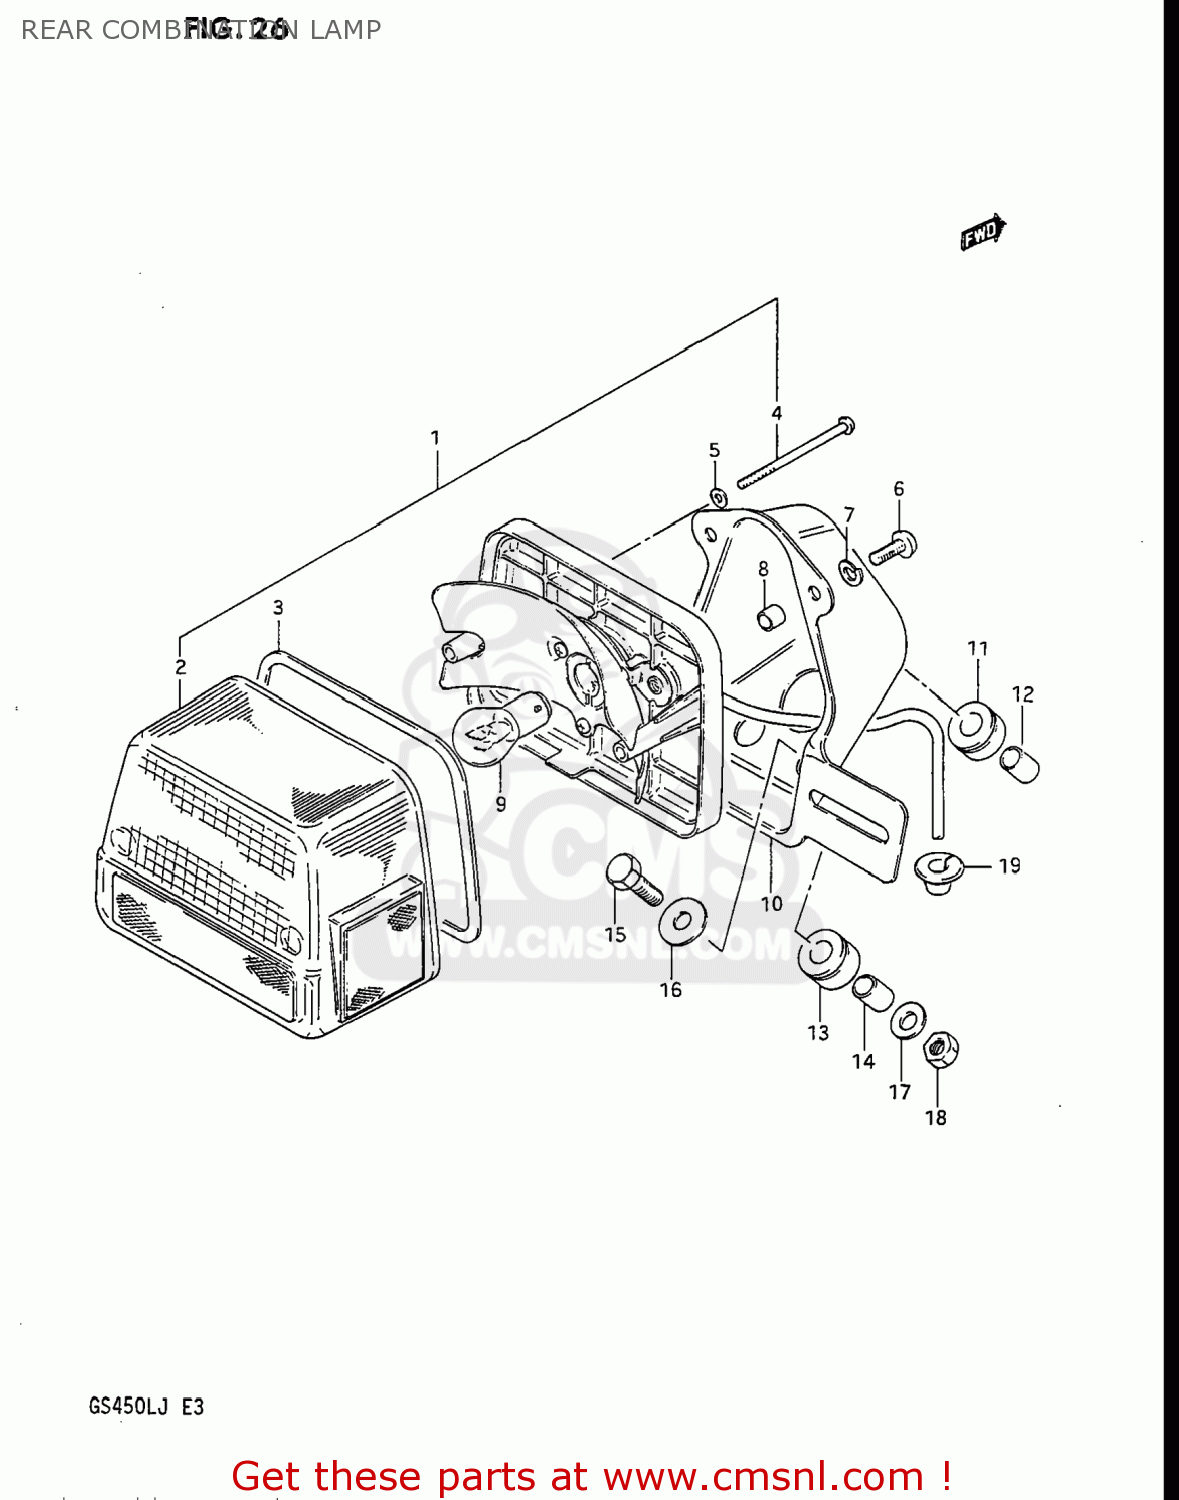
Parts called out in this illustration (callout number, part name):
1	LAMP UNIT,RR COMBNATION
2	LENS
3	GASKET (NAS)
4	SCREW
5	GASKET (NAS)
6	SCREW
7	LOCK WASHER
8	SPACER
9	BULB(12V23W)
10	BRACKET,REAR COMBINATION LAMP
11	CUSHION
12	SPACER
13	CUSHION,REAR COMBINATION LAMP
14	SPACER,REAR COMBINATION LAMP
15	BOLT
16	WASHER (6.5X20X1.2)
17	WASHER, LOWER
18	NUT
19	GROMMET
